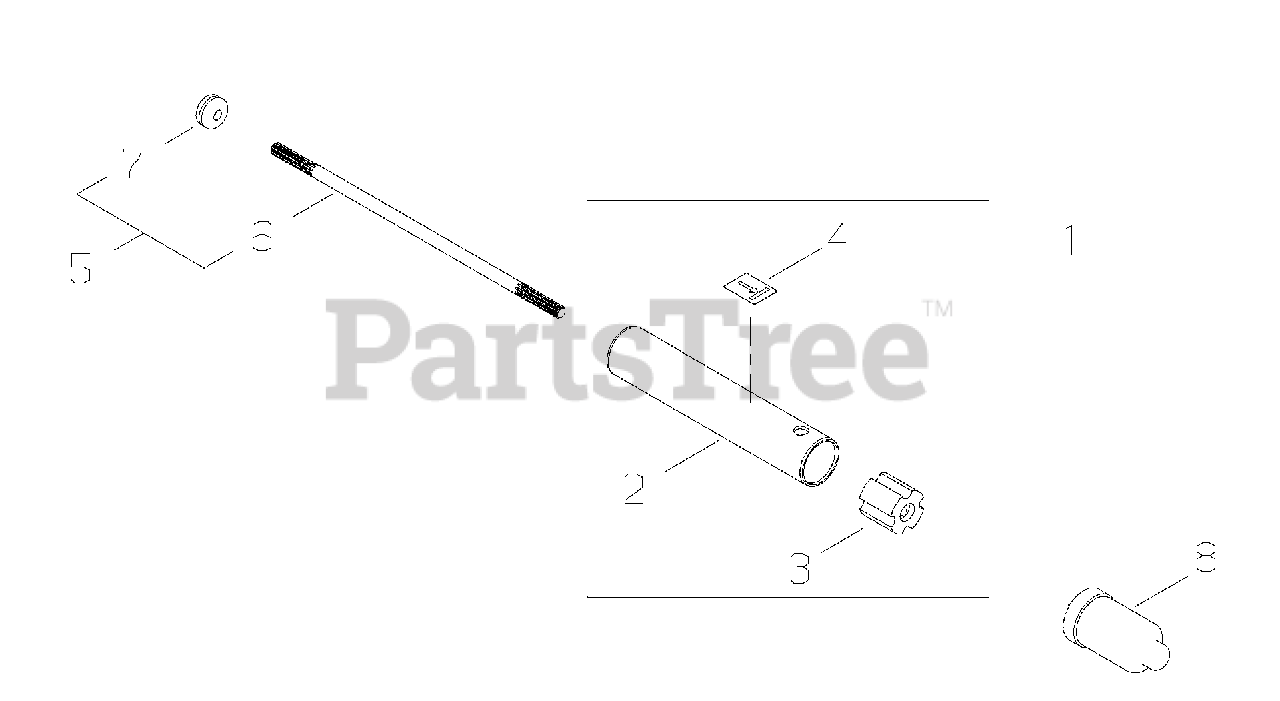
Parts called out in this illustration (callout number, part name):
1	MAIN PIPE ASSY
2	PIPE - OUTER
3	BUSHING
4	LABEL - ALIGNMENT
5	MAIN PIPE ASSY
6	PIPE, MAIN
7	GROMMET
8	CAP
